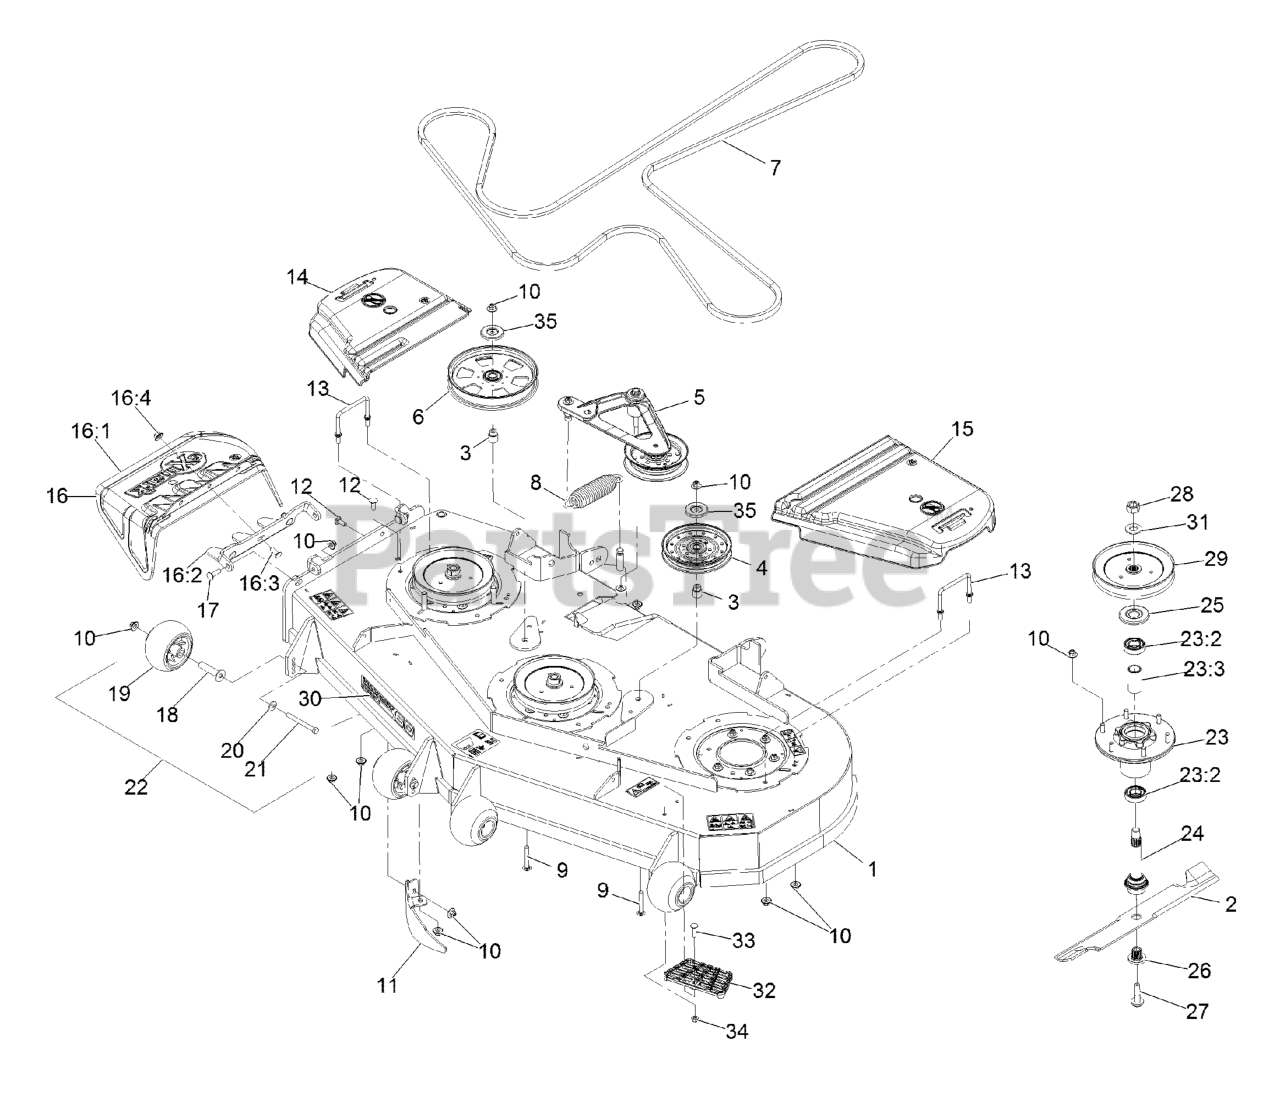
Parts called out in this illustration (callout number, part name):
1	DECK ASM,W/DECALS 60
2	Blade-Extreme 2, 20.50"
3	BUSHING-IDLER
4	IDLER-PULLEY
5	DECK IDLER ASM
6	PULLEY-IDLER, FLAT
7	BELT,V-5V-198.75
8	SPRING-EXTENSION
9	SCREW-CARR
10	Nut-Nyloc 3/8-16 Flg
11	DOGLEG - LZ60
12	SCREW-CARR
13	WIREFORM-COVER
14	COVER-BELT, RH
15	COVER-BELT, LH
16	ASM,DISCHARGE CHUTE
16:1	CHUTE,DISCHARGE
16:2	BRACKET,DISCHARGE CHUTE
16:3	SCREW-CARR
16:4	Nut-Nyloc 3/8-16 Flg
17	Bolt-Carriage 3/8-16 X 1 1/4
18	AXLE, ROLLER
19	ROLLER-SCALP, ANTI
20	WASHER-BELLEVILLE
21	SCREW-HH 3/8-16 X 3 3/4 GR 8
22	KIT, ANTI-SCALP ROLLER
23	ASM-CUTTER HSG WITH BEARINGS
23:2	BEARING-BALL
23:3	SPACER-BEARING
24	ASM-SPINDLE AND SEAL
25	GUARD,BEARING TOP .989
26	BUSHING,SPLINED
27	SCREW,SEMS 1/2-20 X 2.19
28	NUT-HEX
29	SHEAVE,BLADE DRIVE 7.25
30	DECAL, 604
32	STEP-DECK
33	Bolt-Carriage 5/16-18 X 1 1/4
34	NUT-HF, NI
35	SHIELD-DUST
